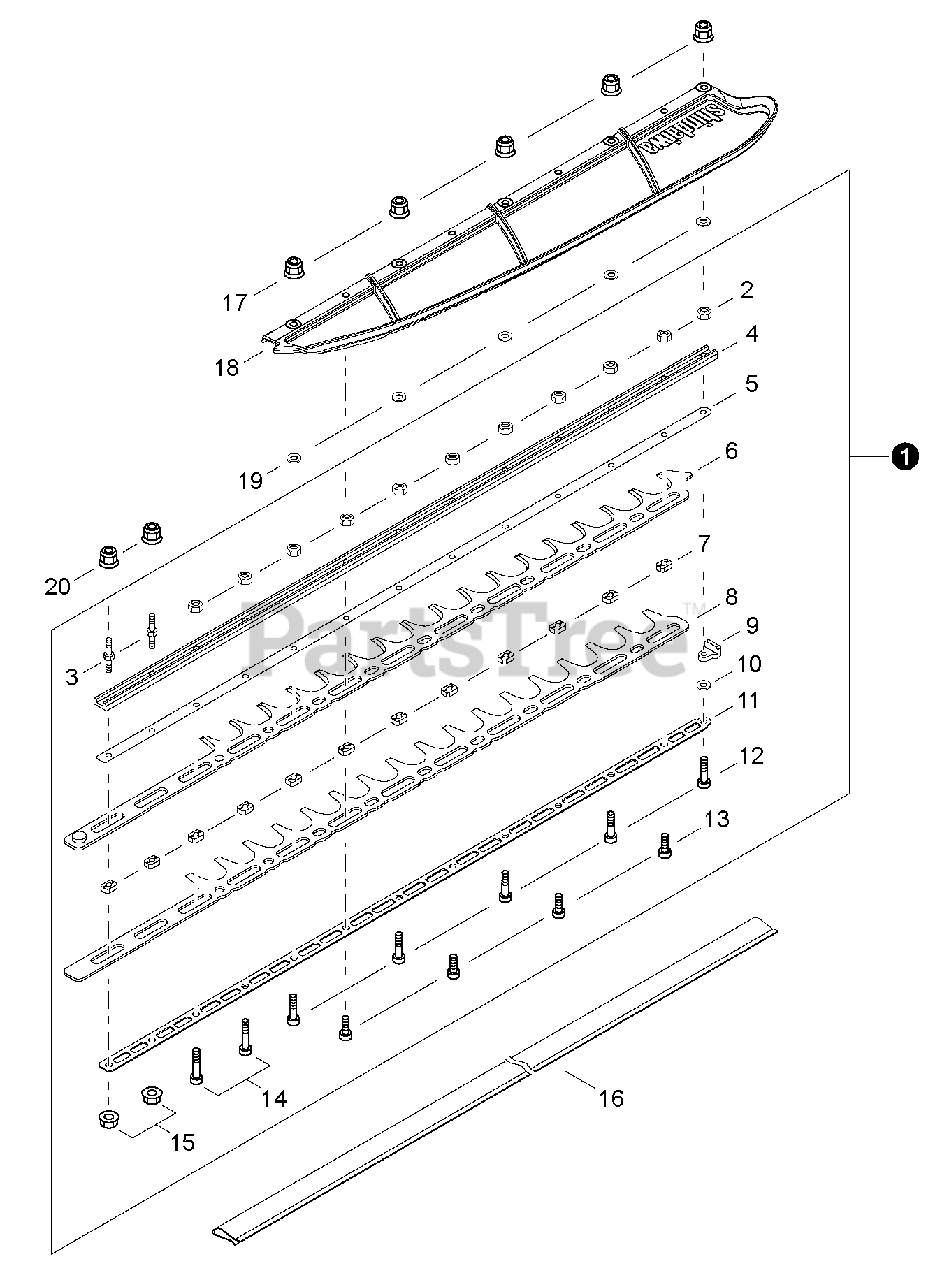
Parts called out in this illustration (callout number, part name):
1	BLADE ASSY - 40" (101cm)
4	SUPPORT, BLADE - 40" (101cm)
5	SUPPORT, BLADE - 40" (101cm)
6	BLADE - 40" (101cm)
8	BLADE - 40" (101cm)
11	SUPPORT, BLADE - 40" (101cm)
12	SCREW - 5X25
13	SCREW - 5X16
14	SCREW - 5X30
15	NUT - 5
16	COVER, BLADE
17	NUT - 5
18	DEFLECTOR, DEBRIS
19	WASHER - 5
20	NUT - 5
